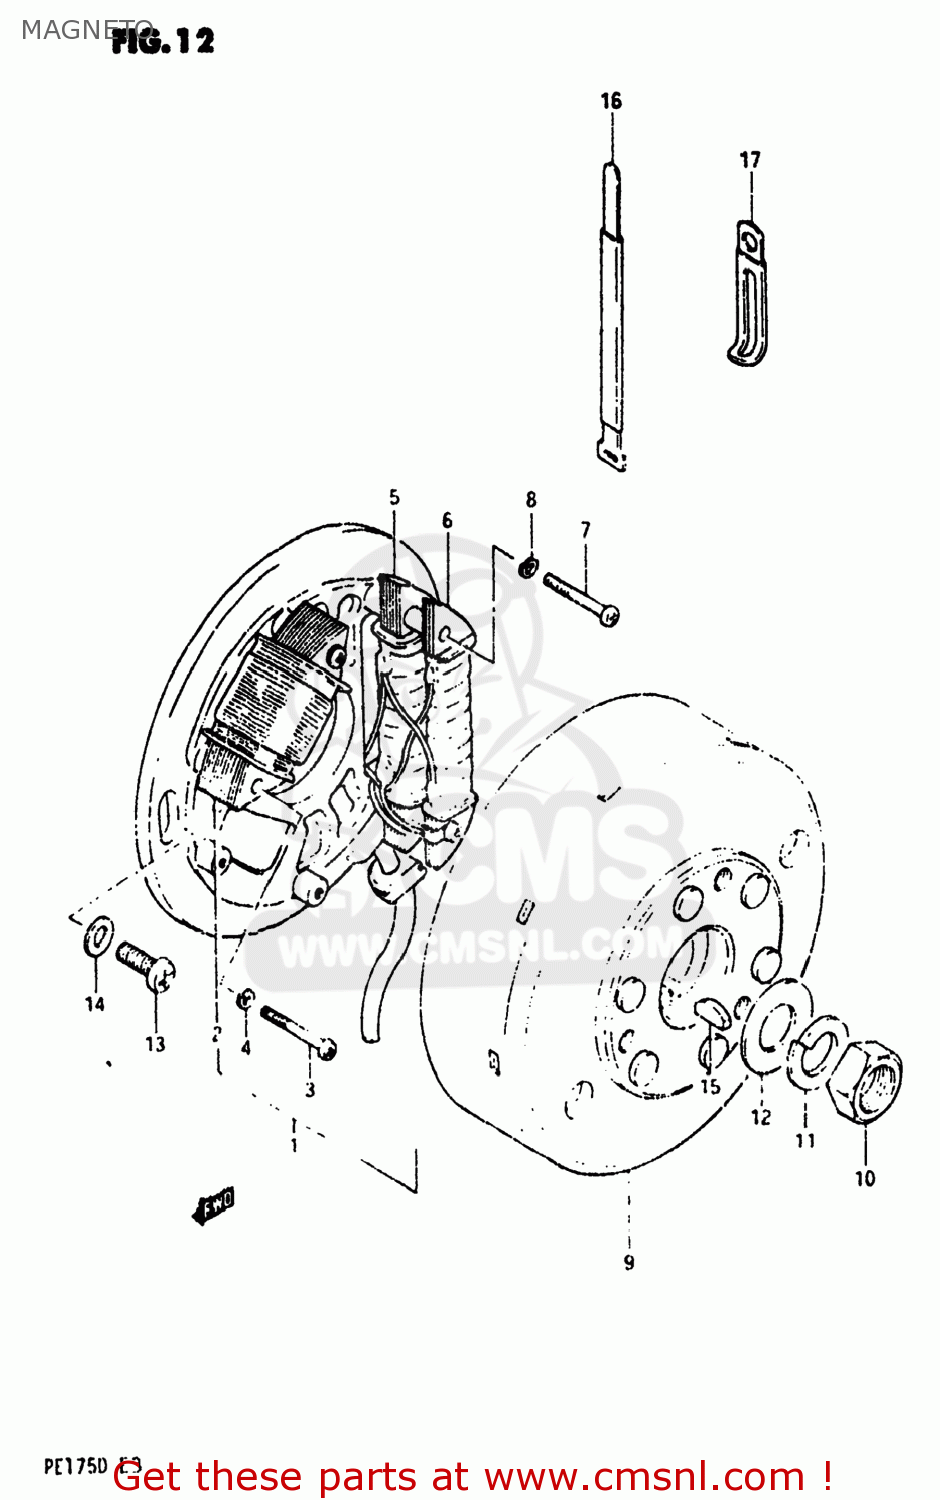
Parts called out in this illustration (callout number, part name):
1	STATOR ASSEMBLY
2	COIL,LIGHTING
3	SCREW (4X30)
4	LOCK WASHER
5	COIL
6	COIL,PRIMARY
7	SCREW (4X30)
8	LOCK WASHER
9	ROTOR ASSEMBLY
10	NUT (10MM)
11	LOCK WASHER
12	WASHER
13	SCREW
14	WASHER
15	KEY 4MM
16	CLAMP L:110
17	CLAMP
